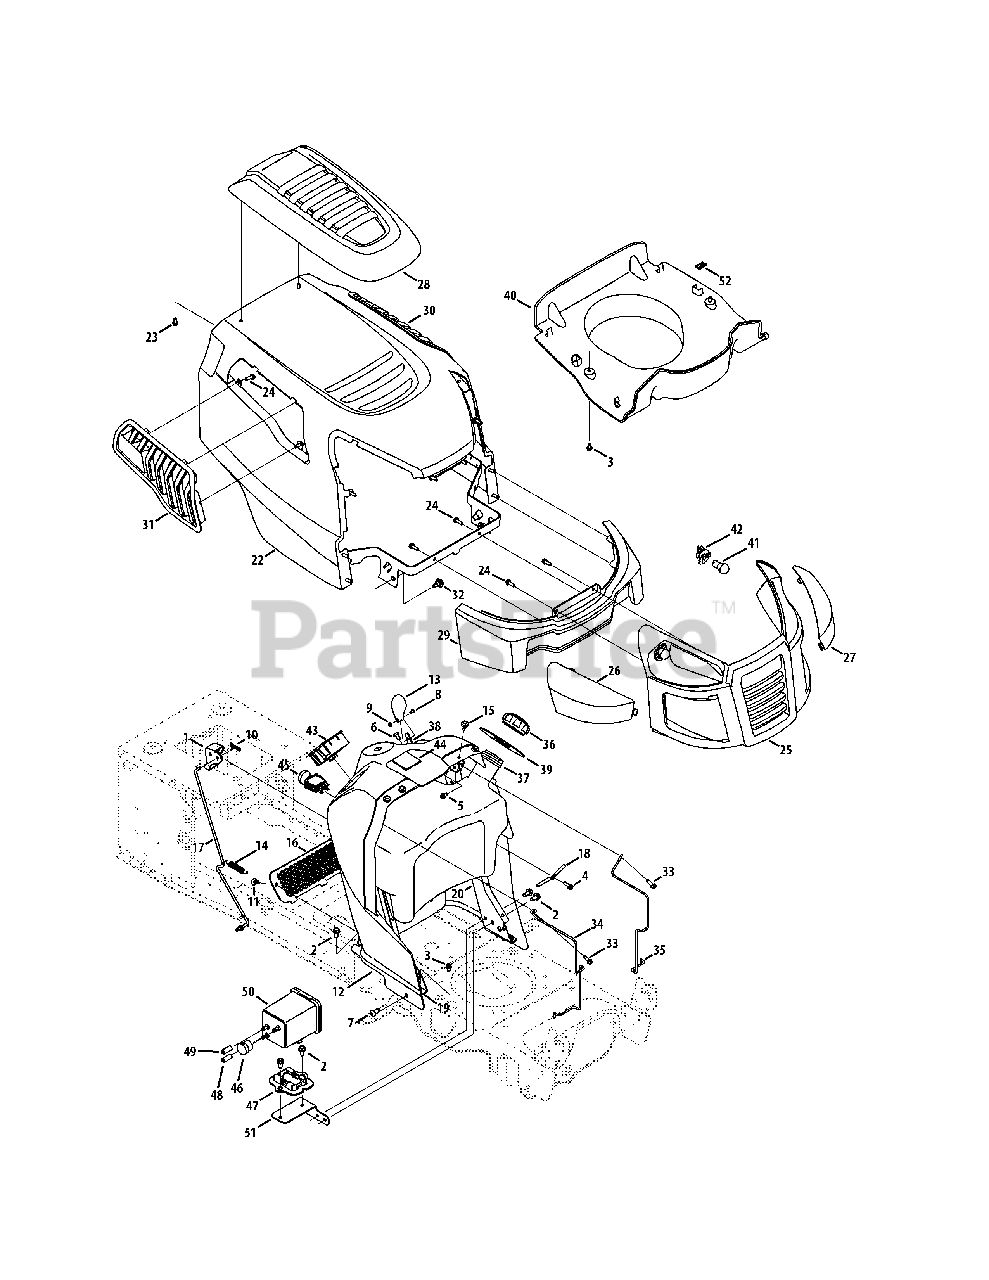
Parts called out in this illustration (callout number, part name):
1	Dash Lever
2	Taptite Screw, Lock Washer, 5/16-18:.750
3	Taptite Screw, Lock Washer, 1/4-20:0.500
4	Hi-Lo Screw, Lock Washer, 1/4-15:0.750
5	Screw, Lock Washer, 1/4-20:0.625
6	Screw, 1/4-14:0.625
7	Taptite Screw, 5/16-18:0.750
8	Machine Screw, #8-32:0.375
9	Hex Nut, #8-32:GRA
10	Bow-tie Cotter Pin
11	Ratchet Clip:.250 DIA
13	Control Knob
14	Extension Spring, .500 DIA X 2.733 LG
15	Bumper
16	Accessory Net
17	Control Rod Latch
18	Lever Rod
19	RH Dash Support Plate
20	LH Dash Support Plate
21	Keys (Set of 2)
22	Hood Assembly
23	Hi-lo Screw, Lock Washer, 1/4-15:0.50
24	Screw, Lock Washer, 1/4 DIA:.750
26	RH Lens
27	LH Lens
28	Hood Scoop
29	Lower Grill
30	LH Hood Scoop
31	RH Hood Scoop
32	Shoulder Screw, .43X.29:TT:5/16-18
33	Taptite Screw, 1/4-20:0.750
34	RH Tank Support Rod
35	LH Tank Support Rod
36	Fuel Cap
37	Fuel Tank
38	Throttle/Choke Control
39	Fuel Tank Gasket
40	P-Style Plen
41	Miniature Lamp, 12V
42	Lamp Socket
43	Switch Key Module
44	Hour Meter
45	PTO Switch
46	Canister Filter Vent
47	Canister Adapter Bracket
48	Low Permeated Fuel Line, 3/16 White
49	Low Permeated Fuel Line, 7/32 Yellow
50	Carbon Canister
51	Carbon Canister Mounting Bracket
